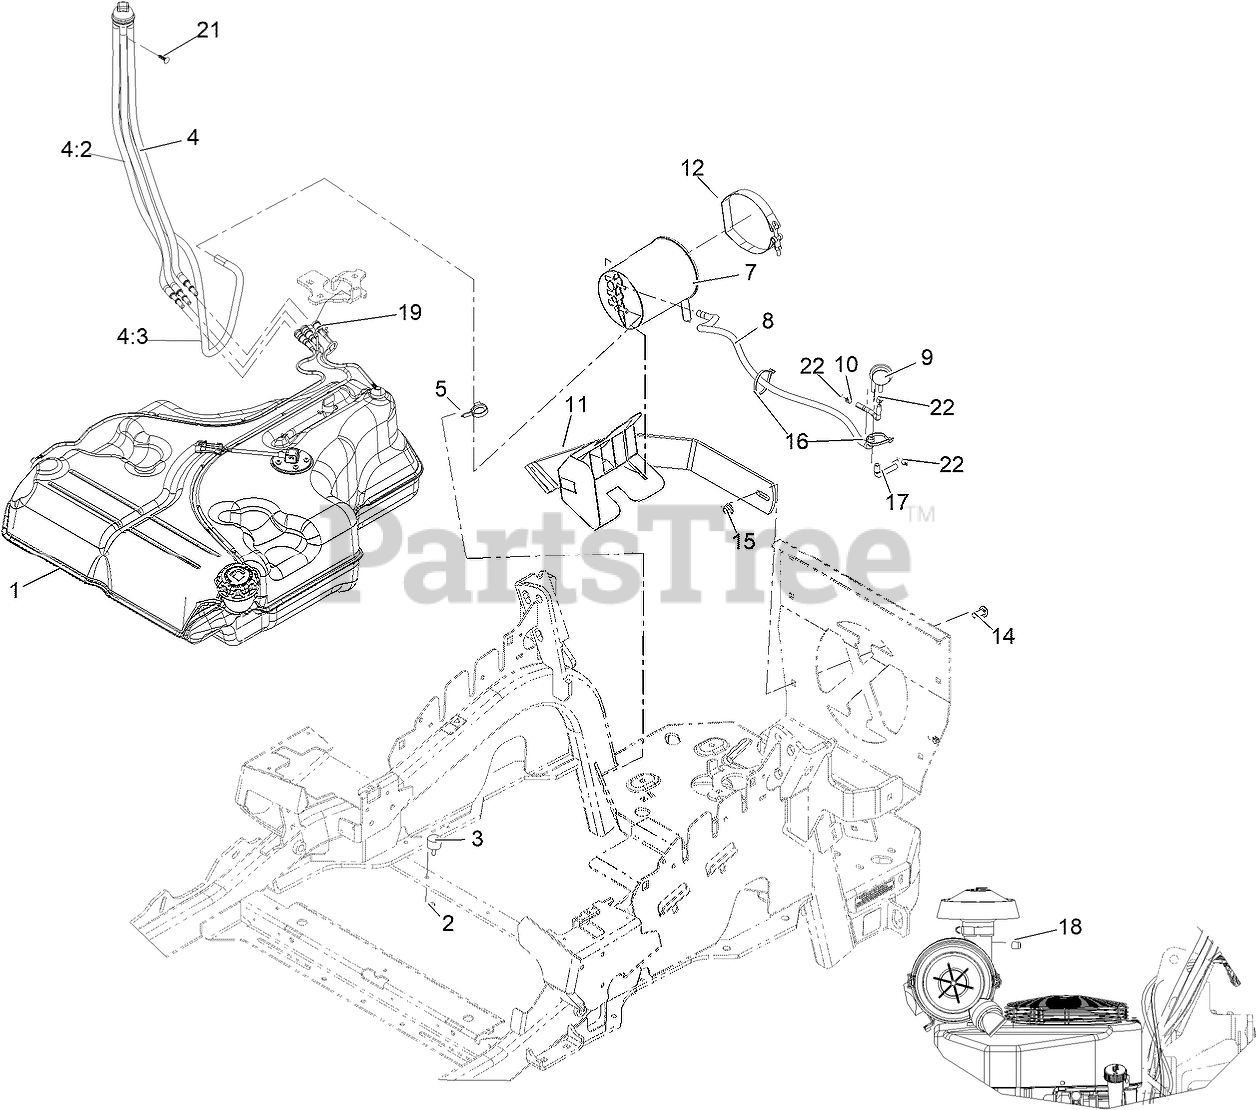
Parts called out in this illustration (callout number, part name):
1	FUEL TANK ASM
2	NUT-JAM
4	FUEL MANIFOLD VENT ASM
4:2	HOSE-FUEL
4:3	HOSE-FUEL
5	CLAMP-HOSE
7	CANISTER-CARBON, 1200CC
8	HOSE,VENT,FORMED
9	VALVE-CONTROL, VACUUM
10	HOSE-VENT, FORMED
11	MOUNT-CANISTER
12	CLAMP, T-BOLT
14	SCREW-CARR
15	NUT-HF, NI
16	TIE-CABLE
17	HOSE-VENT, FORMED
18	PLUG-PORT
19	RETAINER-LINE, VAPOR
21	PLUG-PLASTIC
22	Clamp - Hose
